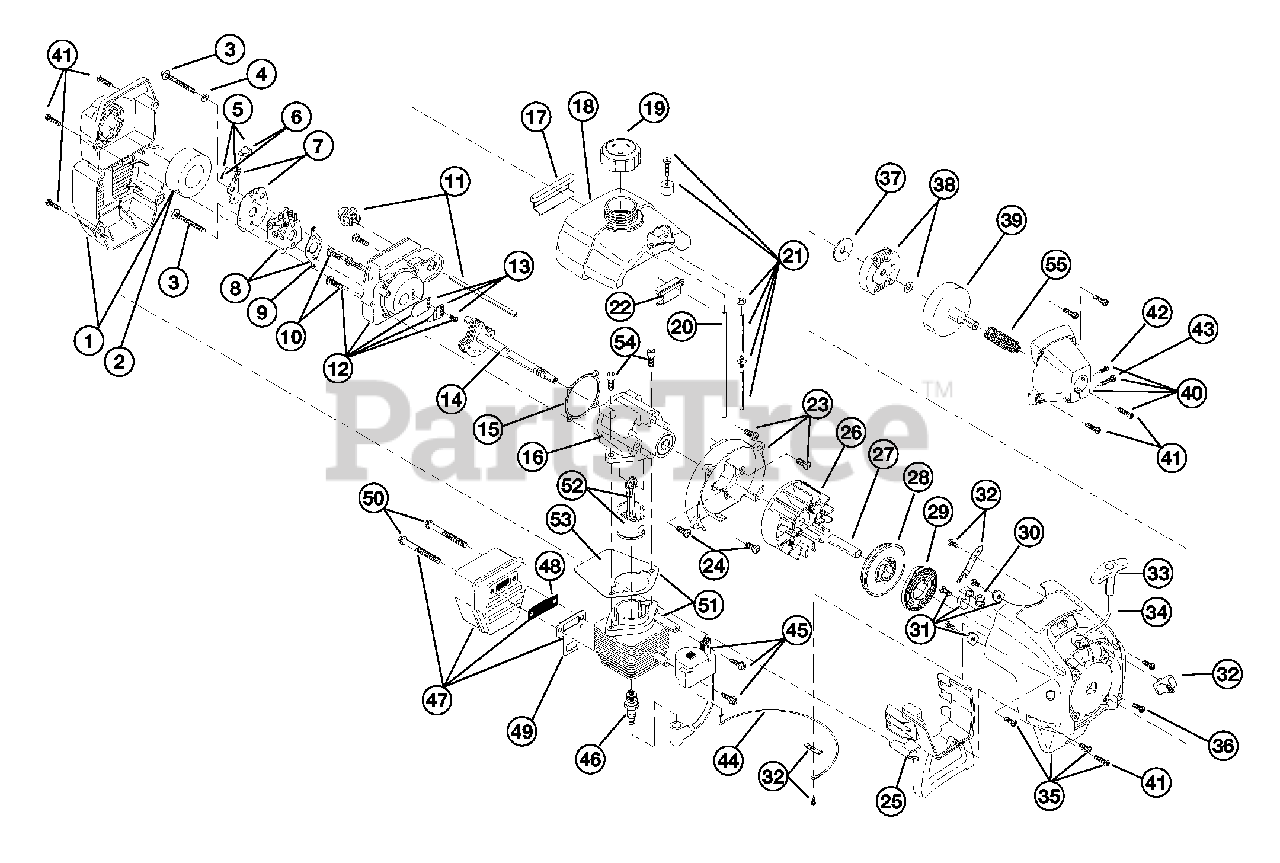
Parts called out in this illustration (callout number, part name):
1	Air Cleaner/Muffler Cover Assembly
2	Air Cleaner Filter
3	Carburetor Mounting Screw Assembly
4	Wavey Washer
5	Choke Lever Assembly
6	Choke Knob and Screw
7	Choke Lever and Plate
8	Carburetor Assembly W/Limiter Caps
9	Carburetor Gasket
10	Carb Mount Screw
11	Primer and Hose Assembly
12	Carb Mount Assembly
13	Reed Assembly
14	Power Shaft Assembly
15	Carburetor Mount Gasket
16	Crank Case Service Assembly
17	Rear Mounting Pad
18	Fuel Tank Assembly
19	Fuel Cap Assembly
20	Fuel Return Line
21	Fuel Line Assembly
22	Front Mounting Pad
23	Shroud Assembly
24	Shroud Screw
25	Shroud Extension and Stand
26	Flywheel Assembly
28	Recoil Pulley Assembly
29	Recoil Spring
30	Rope Guide
31	Pulley Retainer Assembly
32	Switch Assembly
33	Pull Handle
35	Starter Housing Assembly
36	Housing Screw
37	Clutch Washer
38	Clutch Rotor Assembly
39	Clutch Drum Assembly
40	Clutch Cover Assembly
41	Cover Screw
42	Anti-Rotation Screw
43	Clamping Screw
44	Wire Lead
45	Module Assembly
46	Spark Plug
47	Muffler Assembly
48	Spark Arrestor Screen
49	Exhaust Gasket
50	Muffler Mounting Bolt Assembly
51	Cylinder Assembly
52	Piston and Rod Assembly
53	Cylinder Gasket
54	Cylinder Bolt
